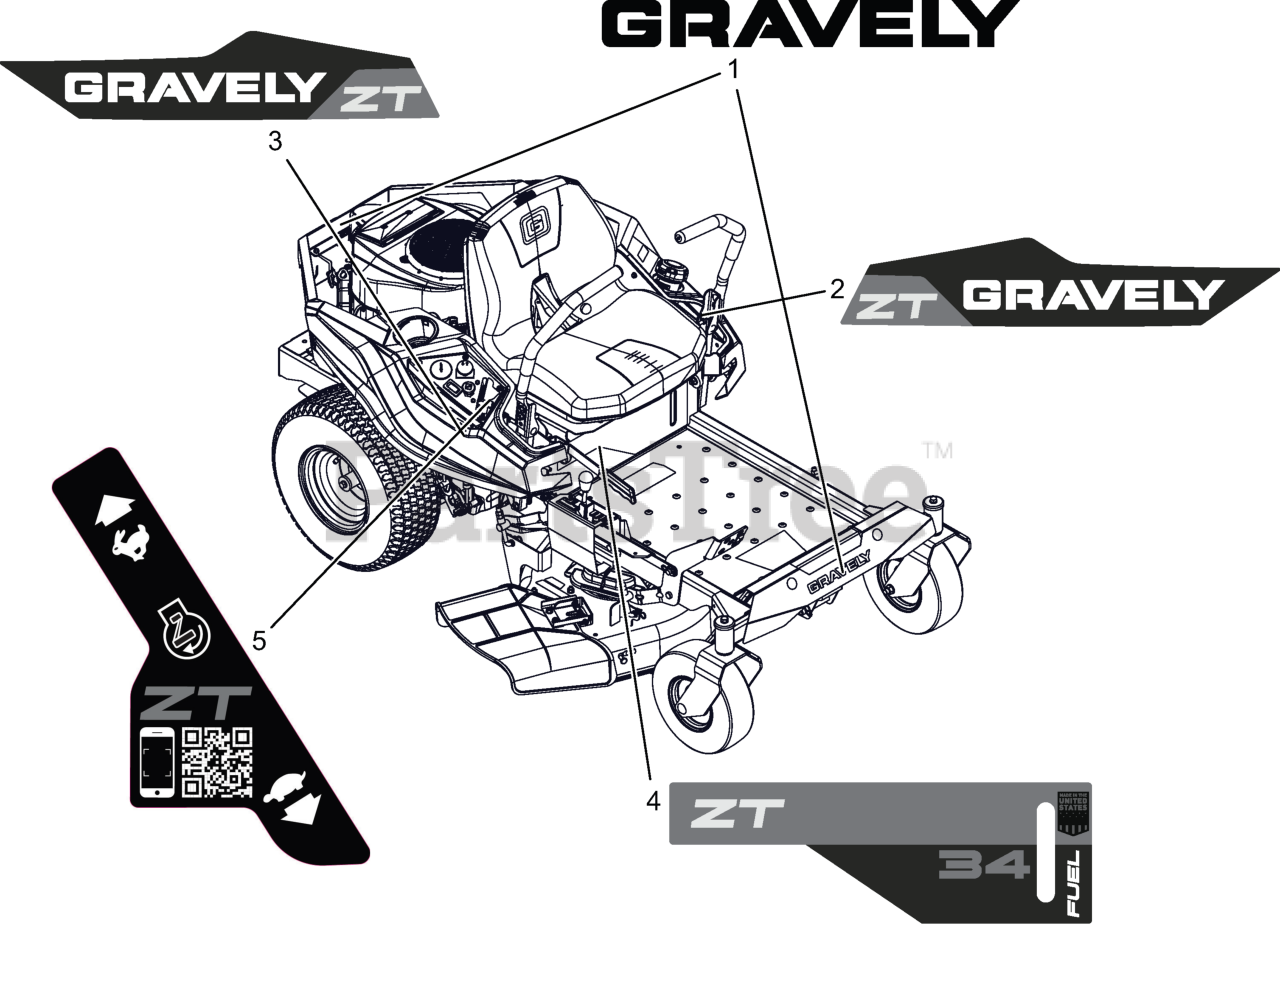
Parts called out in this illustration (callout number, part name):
1	DECAL- GRAVELY
2	DECAL, GRAVELY (FENDER LH)
3	DECAL, GRAVELY (FENDER RH)
4	DECAL, ZT34 KICKPLATE
5	DECAL, THROTTLE CONTORL -ZT
